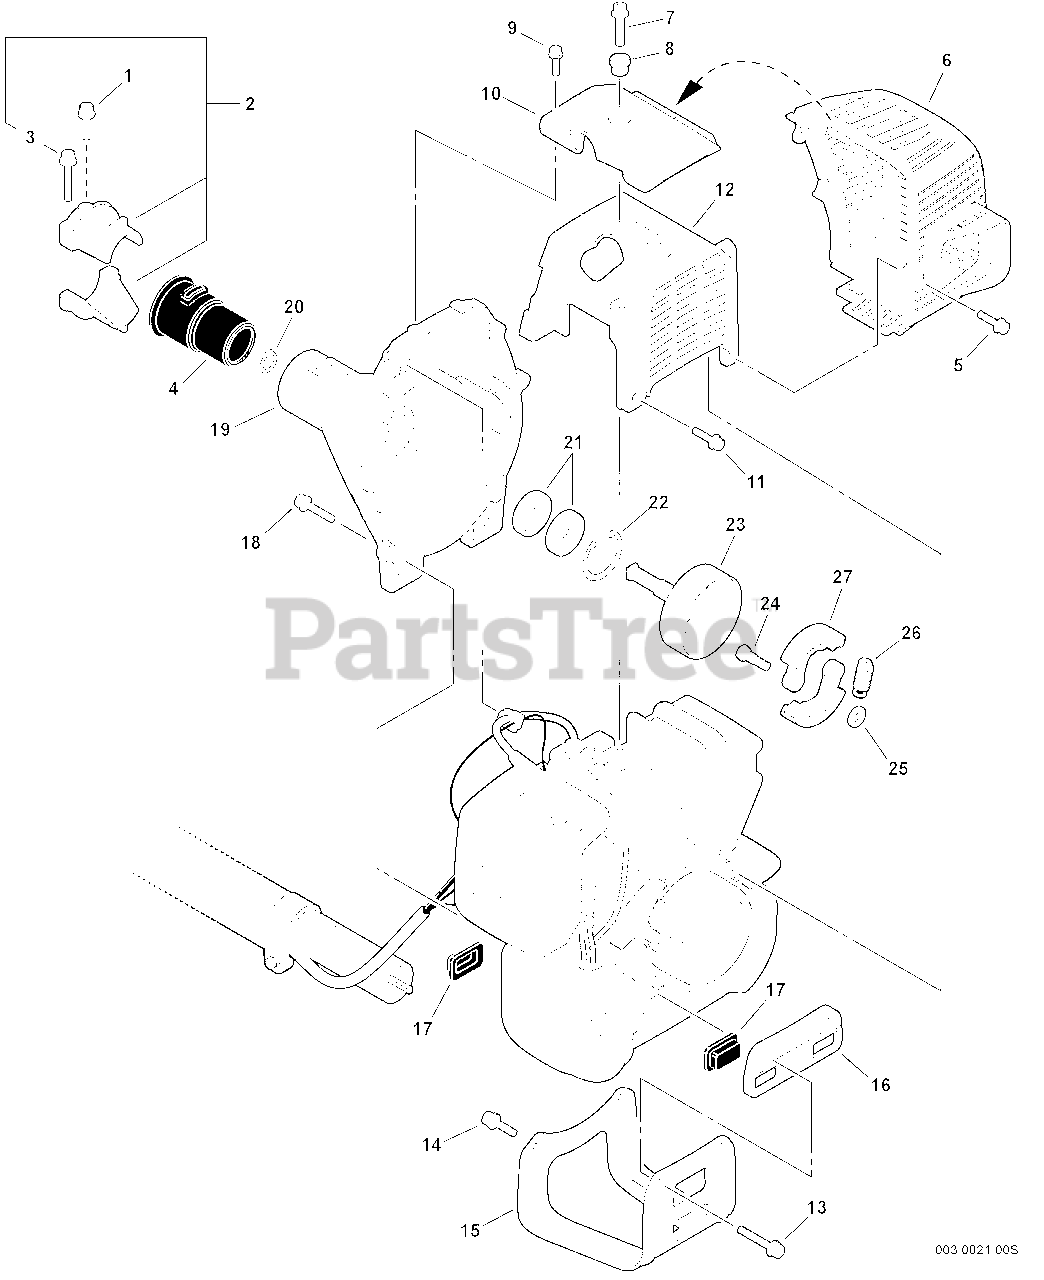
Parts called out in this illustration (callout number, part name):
1	BOLT 5×12
2	RETAINER KIT
3	BOLT 5×25
5	BOLT 5×14
6	COVER, MUFFLER
7	BOLT 5×12
8	COLLAR 5
9	SCREW 4×14
10	GUARD, TOP
11	BOLT 5×12
12	COVER, ENGINE
13	BOLT 5×20
14	BOLT 5×12
15	GUARD, FUEL TANK
16	BRACKET, FUEL TANK
17	CUSHION, FUEL TANK
18	BOLT 5×20
19	COVER, FAN
20	RING, RETAINING - 12
21	BEARING, BALL 6001
22	RING, SNAP 28
23	DRUM, CLUTCH
24	BOLT, CLUTCH M6
25	WASHER 6.2×19×1.0
26	SPRING, CLUTCH
27	SHOE, CLUTCH
